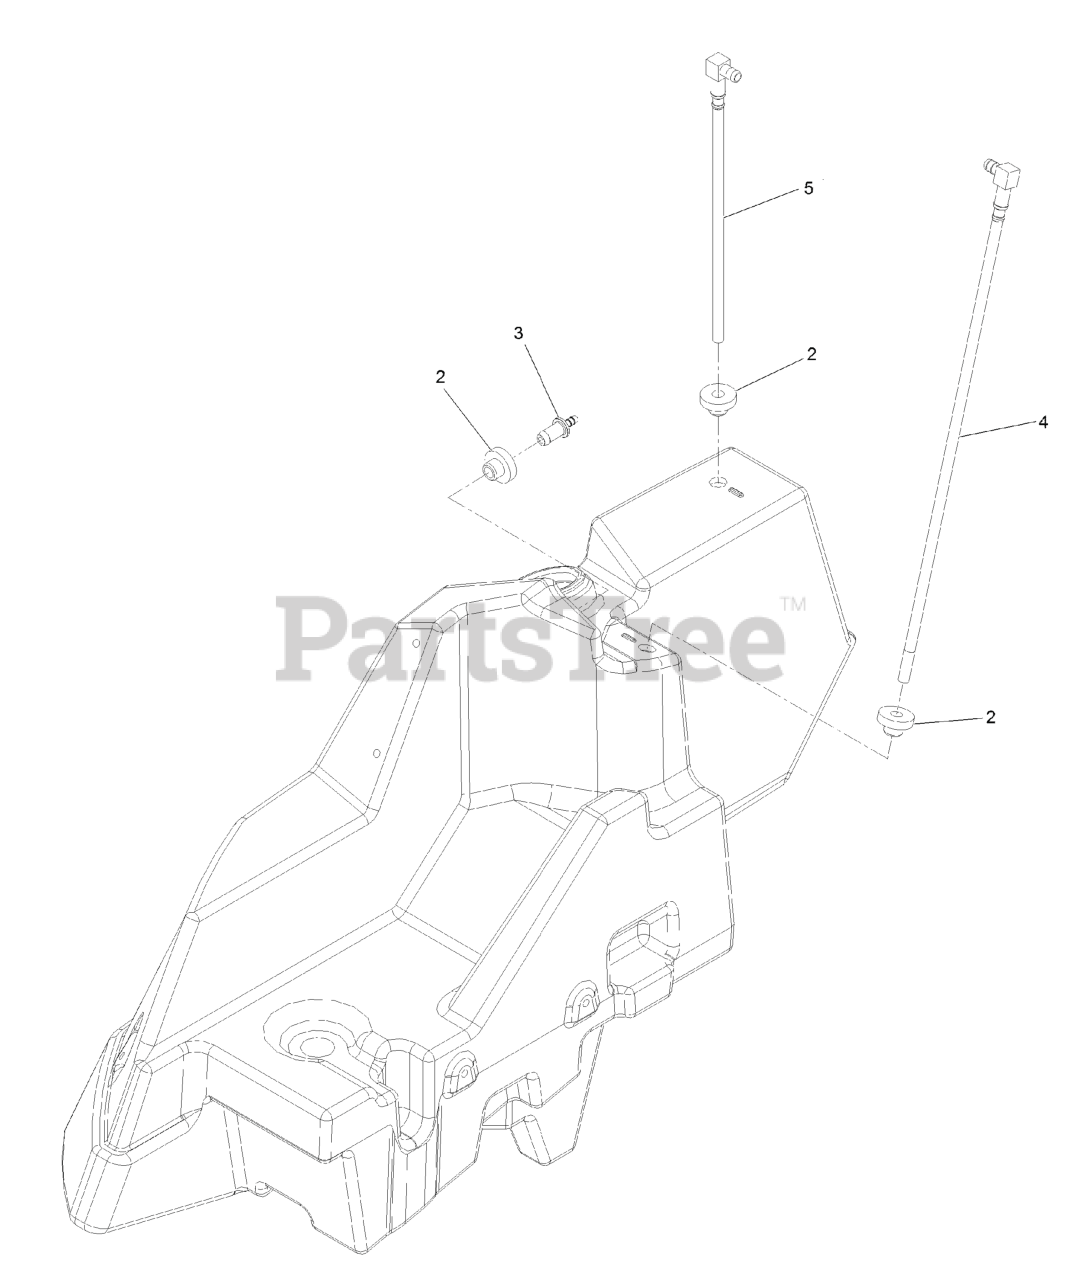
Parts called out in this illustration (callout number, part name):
2	BUSHING
3	FITTING-ORIFICE, STRAIGHT
4	PICK-UP-FUEL
5	RETURN-FUEL
